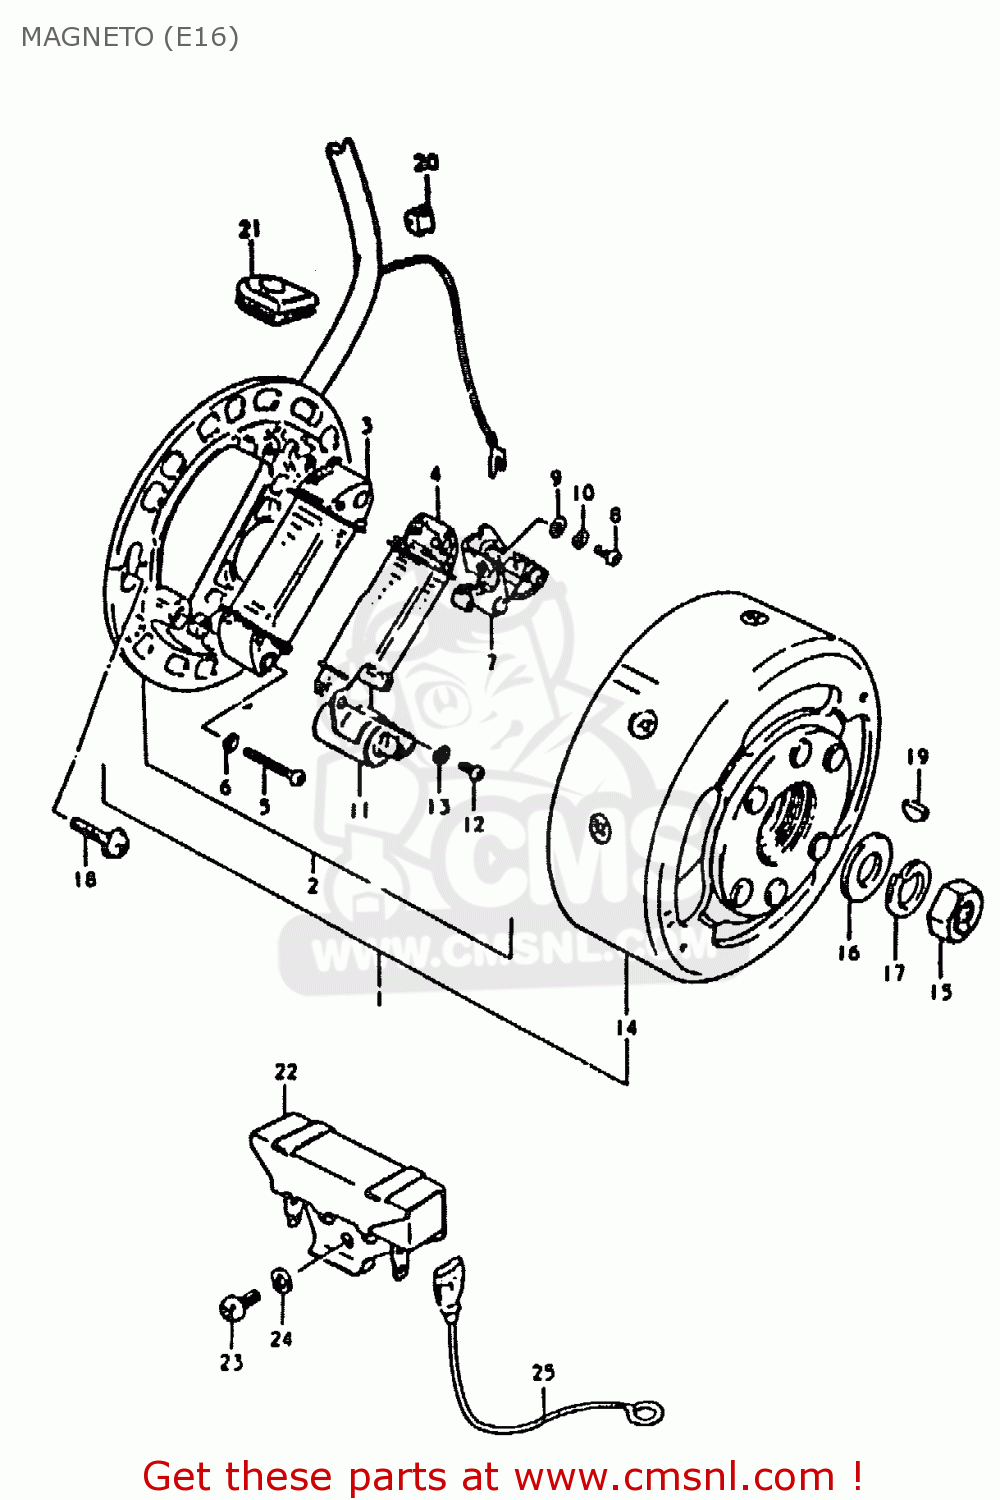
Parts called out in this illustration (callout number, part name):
1	MAGNETO ASSY
2	STATOR ASSY
3	COIL, LIGHTING
4	COIL,PRIMARY
5	SCREW (4X30)
6	LOCK WASHER
7	POINT ASSY,CONTACT
8	SCREW(4X10)
9	WASHER
10	LOCK WASHER
11	CONDENSER
12	SCREW
13	LOCK WASHER
14	ROTOR, FLYWHEEL
15	NUT (10MM)
16	WASHER
17	LOCK WASHER
18	SCREW(5X14)
19	KEY
20	GROMMET,NEUTRAL LEAD WIRE
21	GROMMET
22	RESISTOR ASSY,LAMP(2 OHM)
23	SCREW
24	LOCK WASHER
25	WIRE
